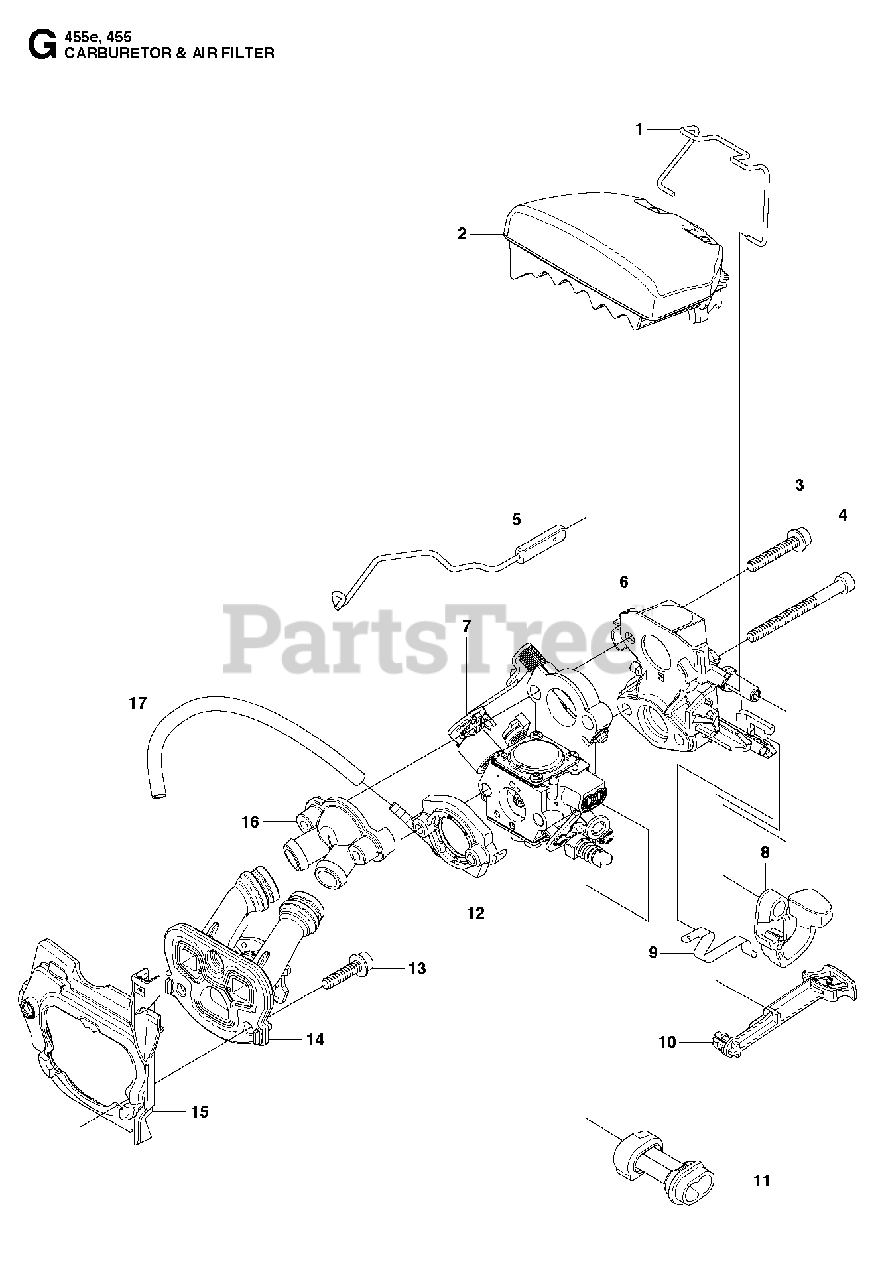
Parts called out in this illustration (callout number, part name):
2	AIR FILTER
5	THROTTLE ROD
6	FILTER HOLDER
7	CARBURETOR
8	STOP LEVER
10	CHOKE CONTROL
11	GUIDE SLEEVE CARB
14	INDUCTION MANIFOLD
17	FUEL HOSE
